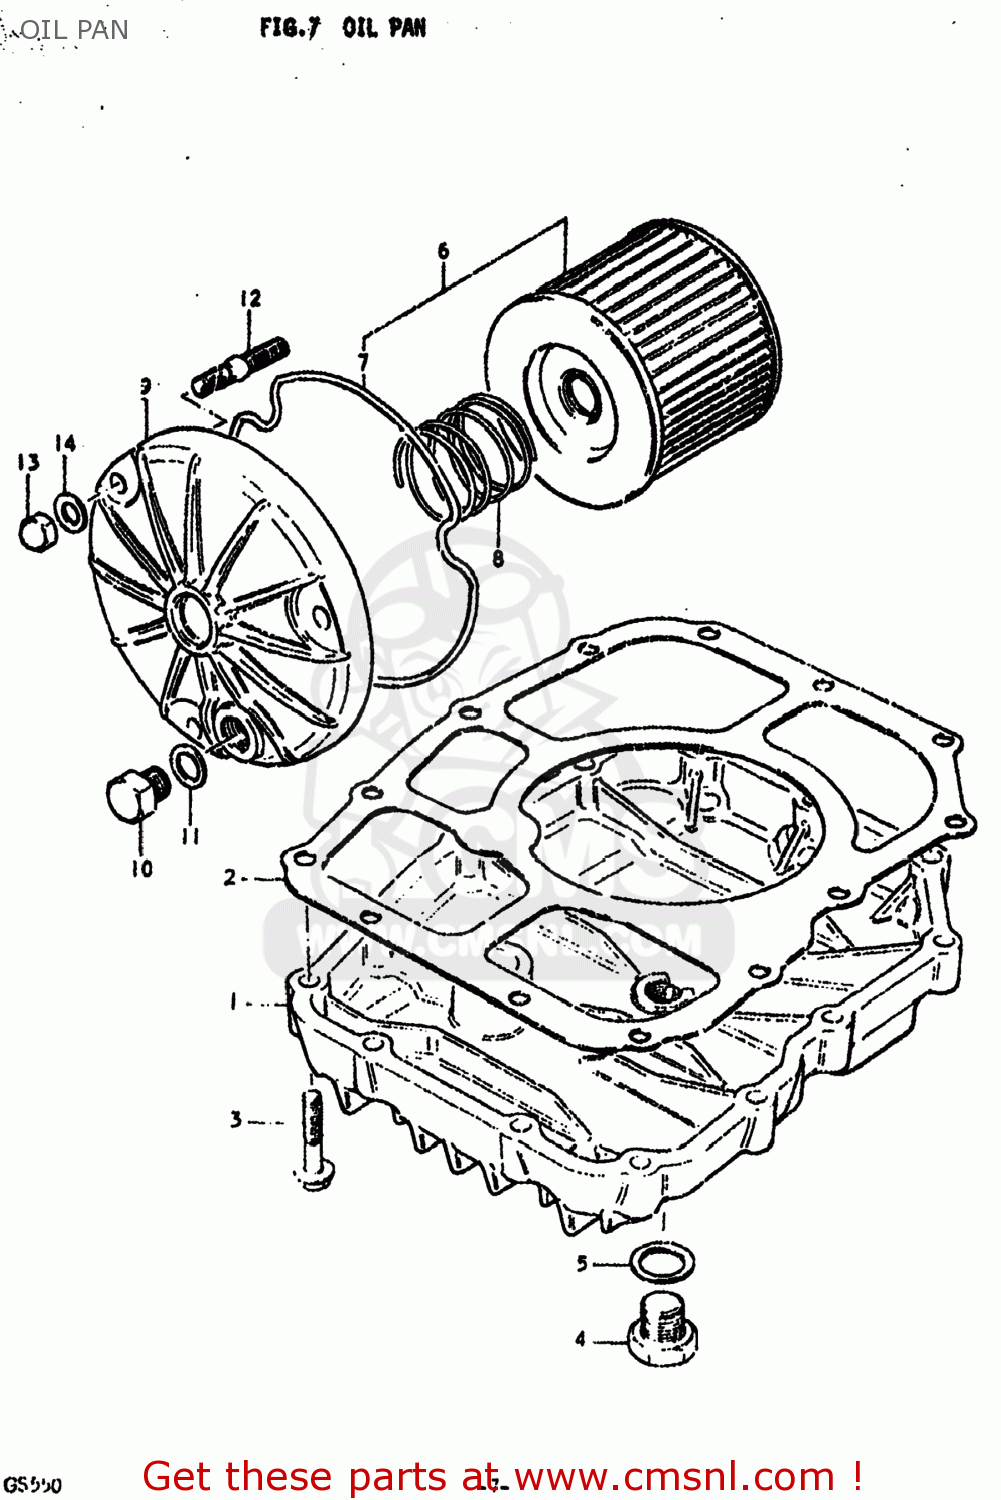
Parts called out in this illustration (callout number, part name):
1	PAN,OIL
2	GASKET,OIL PAN (MCA)
3	BOLT
4	PLUG
5	GASKET(14X19.2X2) (NAS)
6	FILTER ASSY,ENGINE OIL
7	O RING,OIL FILTER CHAMBER CAP
8	SPRING
9	CAP,OIL FILTER
10	PLUG
11	GASKET(10X14X3.6) (NAS)
12	STUD 6X20
13	NUT
14	WASHER
